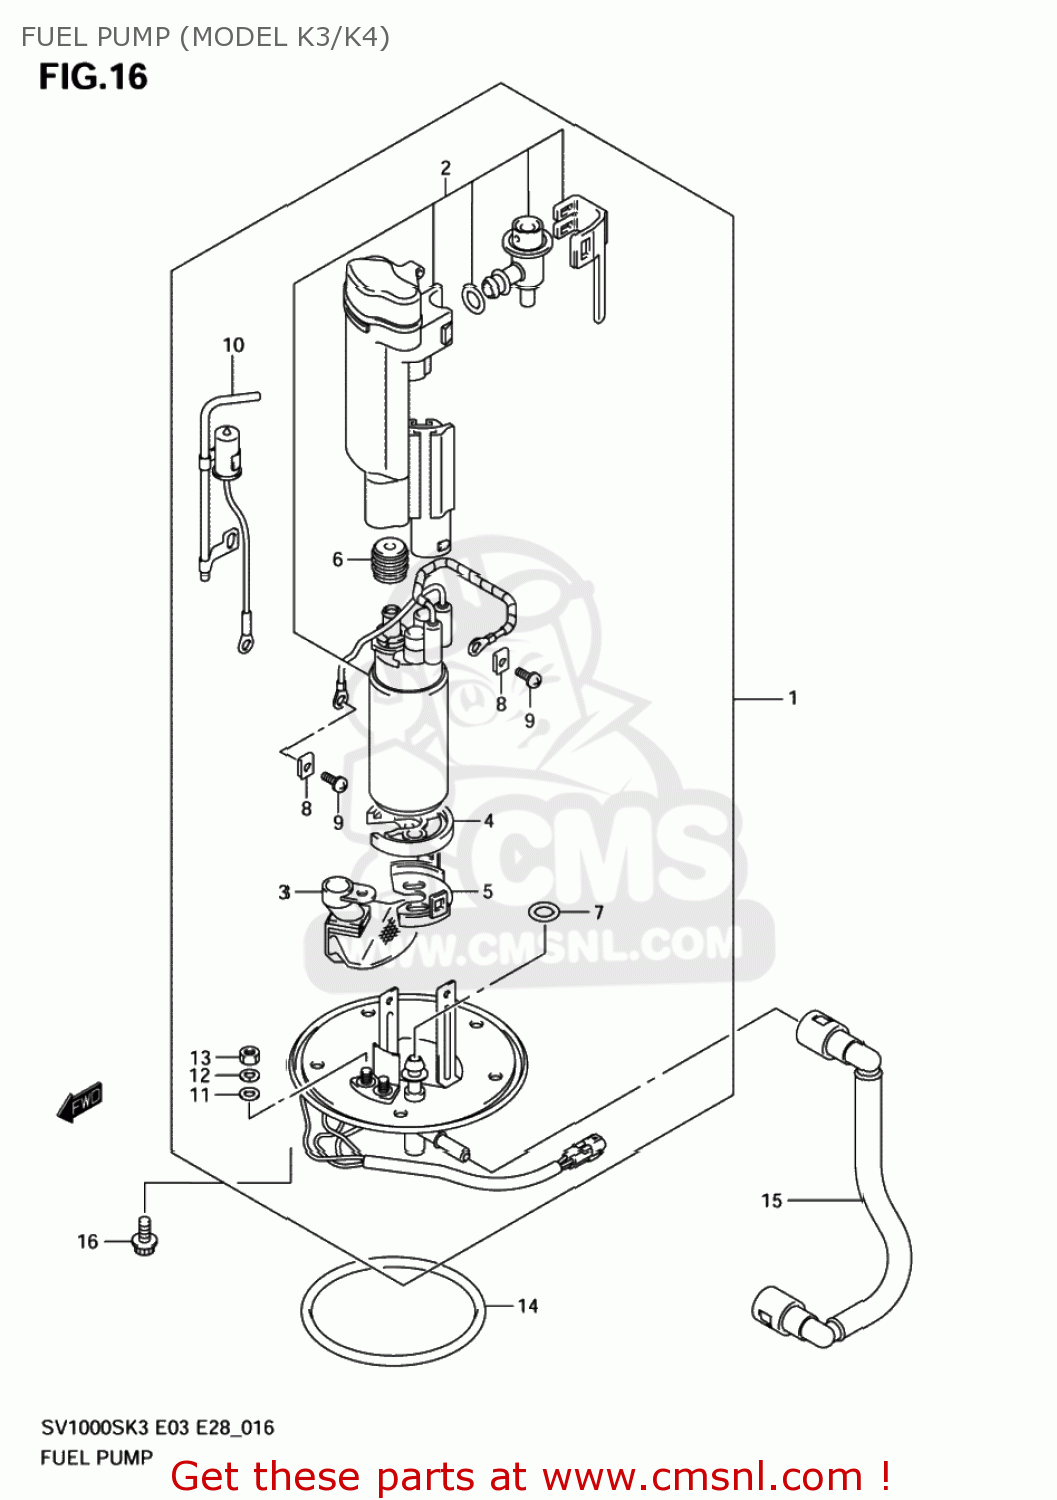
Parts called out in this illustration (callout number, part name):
1	PUMP ASSY,FUEL
2	FILTER ASSY,FUEL
3	STRAINER,FUEL PUMP
4	CUSHION
5	HOLDER,FUEL PUMP
6	BUSH,FUEL PUMP
7	O RING
8	NUT
9	SCREW
10	THERMISTOR
11	WASHER
12	WASHER,SPRING
13	NUT
14	O RING,FUEL PUMP
15	HOSE COMP,FUEL
16	BOLT
